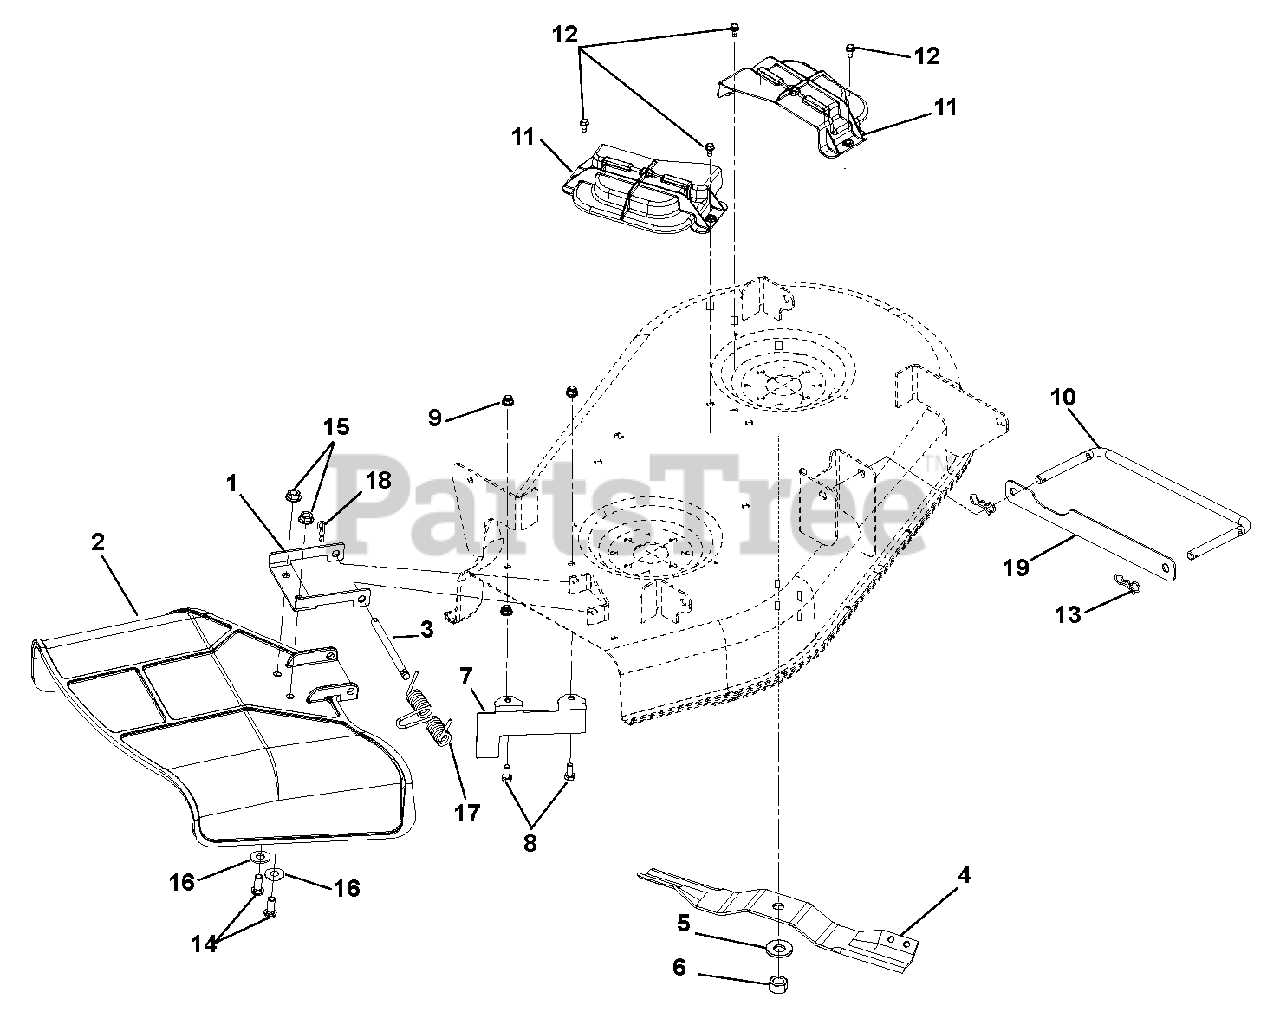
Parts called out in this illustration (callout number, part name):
1	CHUTE REINFORCEMENT
2	CHUTE, SIDE DISCHARGE
3	PIN, 5/16 X 3.88"
4	BLADE, MOWER 17.35
4	BLADE-17.34 OS MULCH
5	WSHR-BLVL .669X1.535X.138
6	NUT-HEX .62-18 YWZC
7	BRKT-BAFFLE, DISCHARGE 34"
8	@BLT-HEX .31-18X.75 GR5 YWZC
9	@NUT-LK-NYL-FLG .31-18 YWZC
10	WIREFORM, DRAG LINK
11	COVER-BELT, MOLDED
12	SCR-TAP .25-20X.50 HWH TR YWZ
13	PIN,BOW TIE LOCKING .091X1.875
14	SCR-SKH .31-18X.75 BTNHD YWZC
15	@NUT-LK-TOP-FLG .31-18 YWZC
16	@WSHR-FL-STL.38X.875X.083 YWZC
17	SPRING, TORSION
18	PIN-HAIR INT .08X.18X1.18 YWZC
19	STRAP, DRAG LINK
